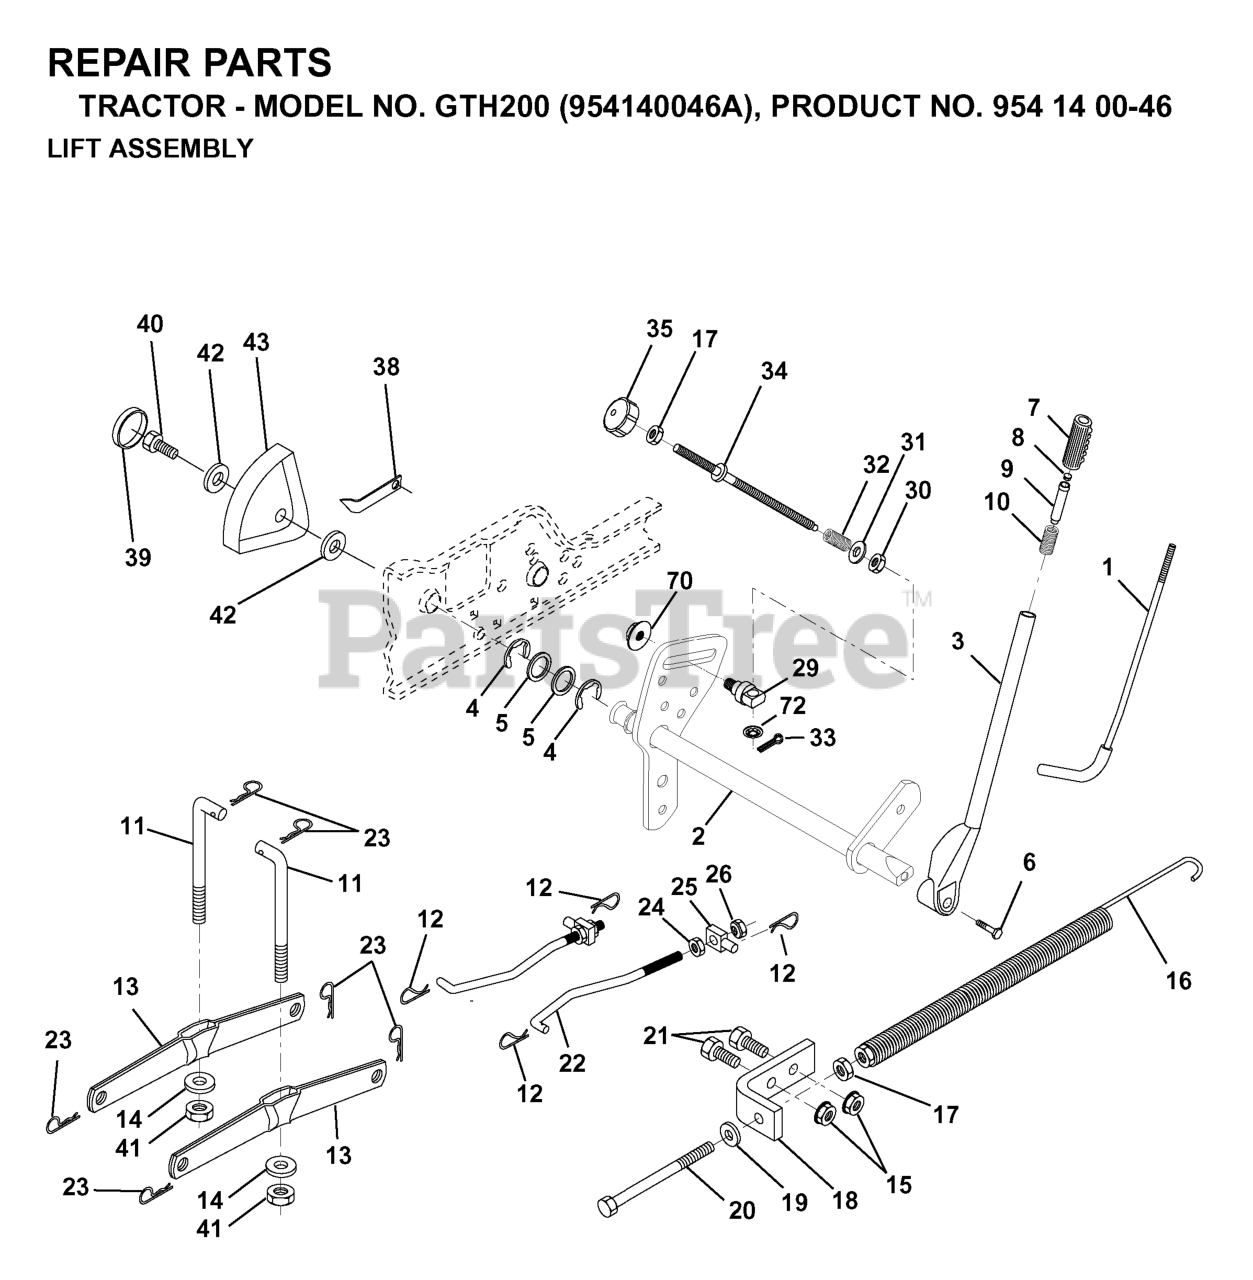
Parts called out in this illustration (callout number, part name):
1	LEVER ROD LT
2	SHAFT ASM., LIFT VGT
3	LIFT LEVER KIT
5	Washer 29/32 x 1 - 1/4 x 16 Ga.
6	BOLT
7	GRIP HANDLE
8	PLUNGER BUT KIT
9	PLUNGER BUT KIT
10	SPRING**
11	LINK LIFT
12	SPRING RETAINER
13	ARM.REAR.SUSPENSION
14	BEARING PIVOT
16	LIFT SPRING
17	NUT
19	WASHER
21	BOLT
22	FRONT LINK
23	RETAINER-SPRNG RB
24	NUT.HEX.JAM.1/2-13
25	TRUNION
26	NUT.LK.W/WSH.1/2.
32	SPRING.COMP.INF.H
33	COTTER PIN
34	ROD.LIFT.ADJUSTABLE
35	KNOB INF 3/8-16
38	POINTER, HEIGHT INDICATOR(2 2)
40	SCREW.THDROL.5/16-18X3/4.TTY
41	NUT CROWNLOCK 3/8-24
43	HEIGHT INDICATOR
70	NUT
72	NUT PUSH M
